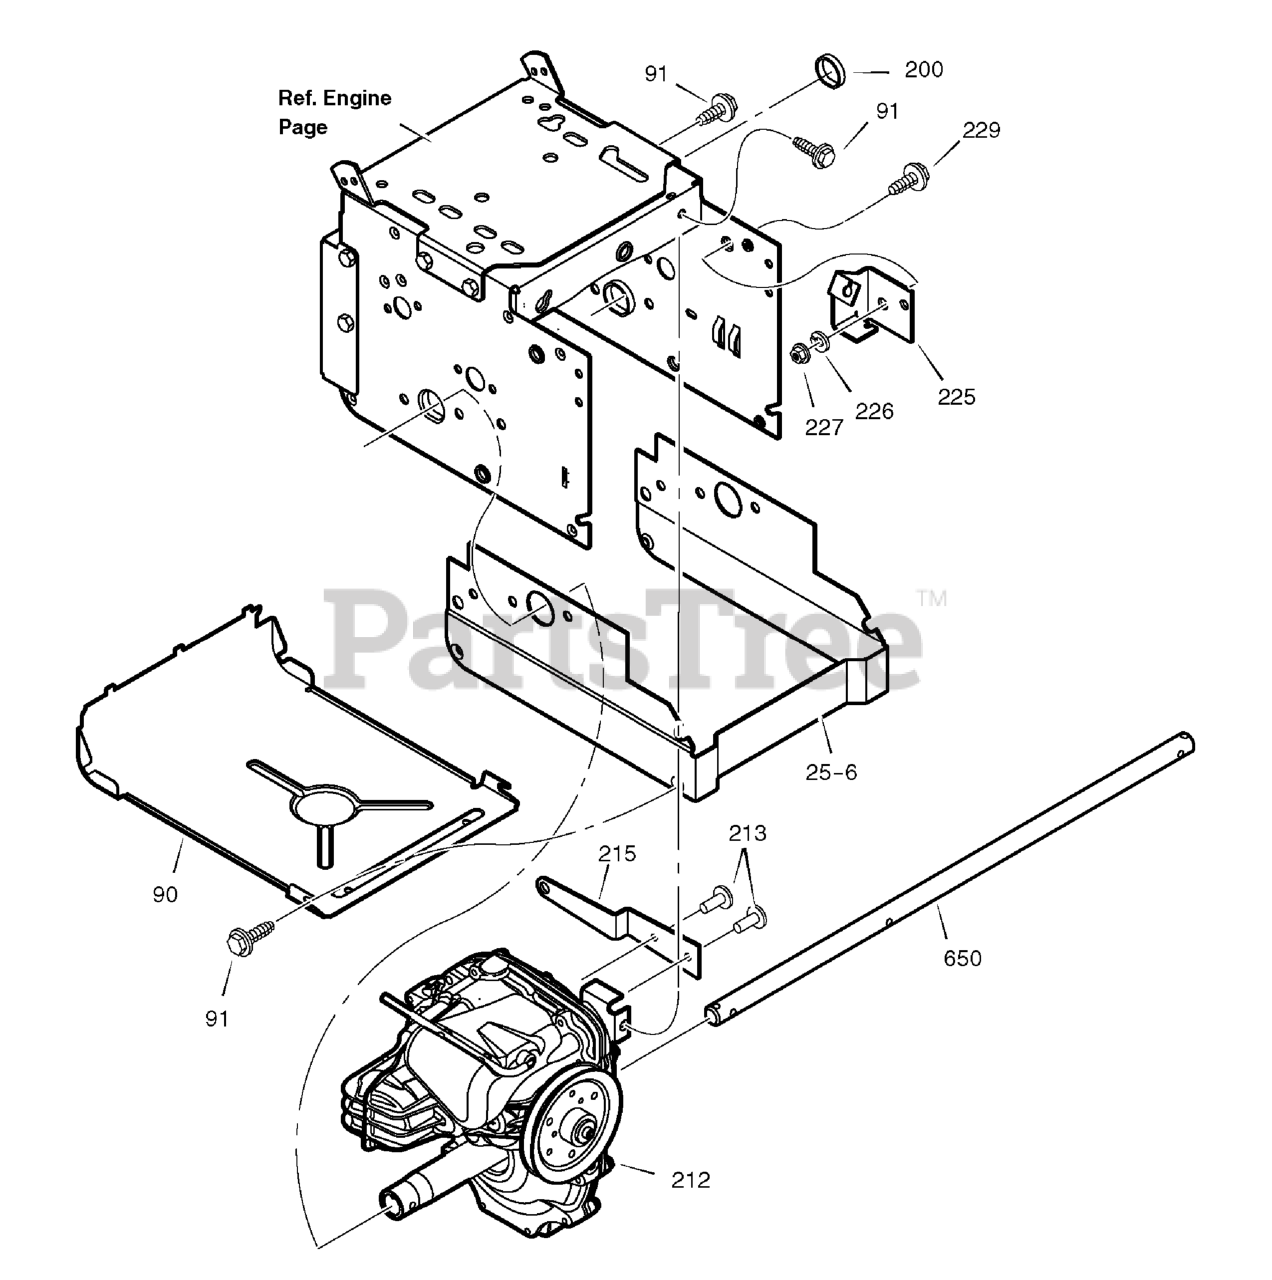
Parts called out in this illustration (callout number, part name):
25-6	FRAME, EXTENSION, HYDRO
90	COVER, BOTTOM
91	SCREW, 1/4-20 X 0.62
200	PLUG, HEYCO
212	Transmission, Hydro *
213	RIVET, BLIND
215	ARM, CONTROL EXTENSION
225	BRACKET, DRIVE CABLE
226	WASHER
227	NUT, HEX JAM - 3/8-16
229	SCREW
650	AXLE, WHEEL
